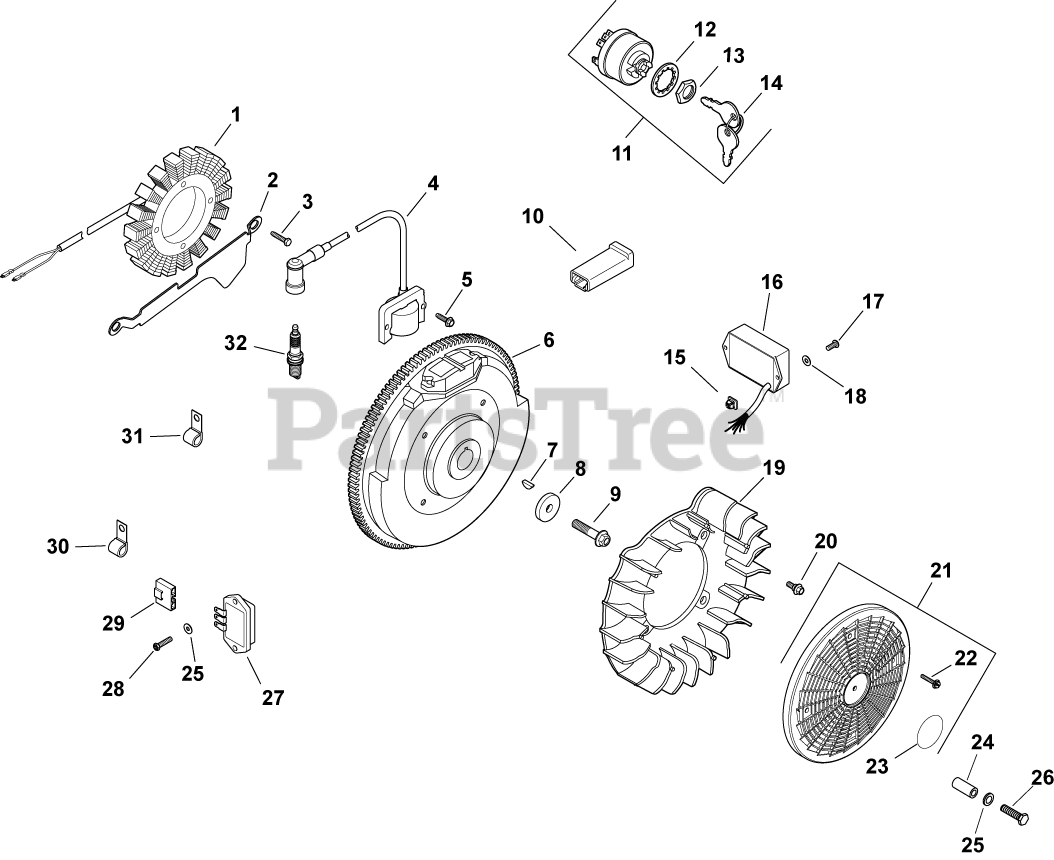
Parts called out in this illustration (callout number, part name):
1	KIT, 15 / 20 AMP STATOR
2	BRACKET, STATOR WIRE
3	SCREW, M5X0.8X25 - (#25086402S)
4	MODULE, IGNITION
5	SCREW, FLG THD FRM M5X.8X20-(#25086399S)
6	FLYWHEEL ASSEMBLY - USE 24 025 14-S
7	KEY, 3/16" X 5/8"
8	WASHER, FLAT 13/32"
9	SCREW, FLG M10X1.5X45 - (#25086361S)
10	CONNECTOR (1 CONTACT)
11	SWITCH ASSY, KEY (KM)-USE 25 099 32-S
12	WASHER, INTERNAL TOOTH
13	NUT, KEY SWITCH
14	KEY, SET -USE 48 340 01-S
15	NUT, PLASTIC
16	MODULE, SPEED ADVANCE-DISCONTINUED SEE PB265
17	SCREW, PHL HD #11-16X1/2"
18	WASHER, FLAT 1/4" (O.D. 1/2")
19	FAN (WITH HOLE)-USE 24 157 16-S
20	BOLT, SHOULDER
21	KIT, GRASS SCREEN
22	SCREW, WSH HD TAP #8-18X1/2"
23	DECAL, GRASS SCREEN USE 24 113 499-S
24	SPACER - DISCONTINUED
25	WASHER, FLAT 3/16"
26	SCREW, SLT HD CAP M4X0.7X25
27	REG/RECTIFIER (20/25 AMP)-USE 25 403 20-
28	SCREW, PHL HD #11-16X7/8"
29	CONNECTOR, BODY (KM)-USE 25 155 41-S
30	CLIP, CABLE
31	CLIP, CABLE - USE 24 154 10-S
32	PLUG, SPARK (PRO SERIES)
